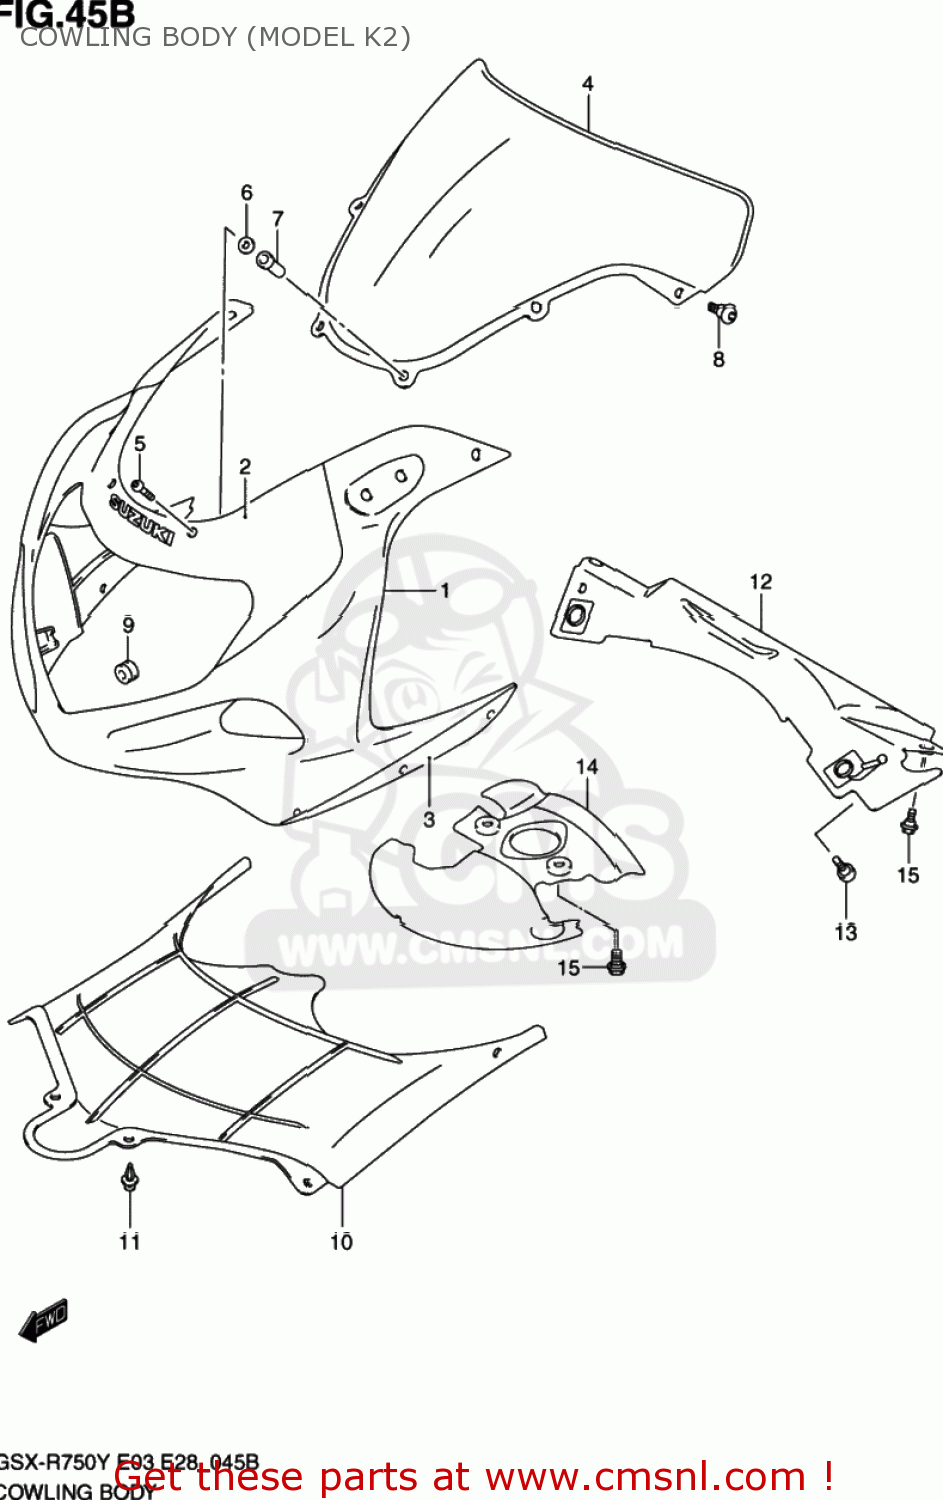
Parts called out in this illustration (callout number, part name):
1	COWLING,BODY(BLUE)
2	TAPE,COWL BODY FR
3	TAPE SET,COWL BODY SIDE
4	WINDSCREEN
5	SCREW(5X14)
6	WASHER
7	NUT
8	SCREW(5X16)
9	CUSHION
10	COVER,BODY COWLING
11	CLIP(BLACK)
12	COVER,COWLING FR LWR
13	BOLT(5X16)
14	COVER,LWR BRACKET
15	BOLT
